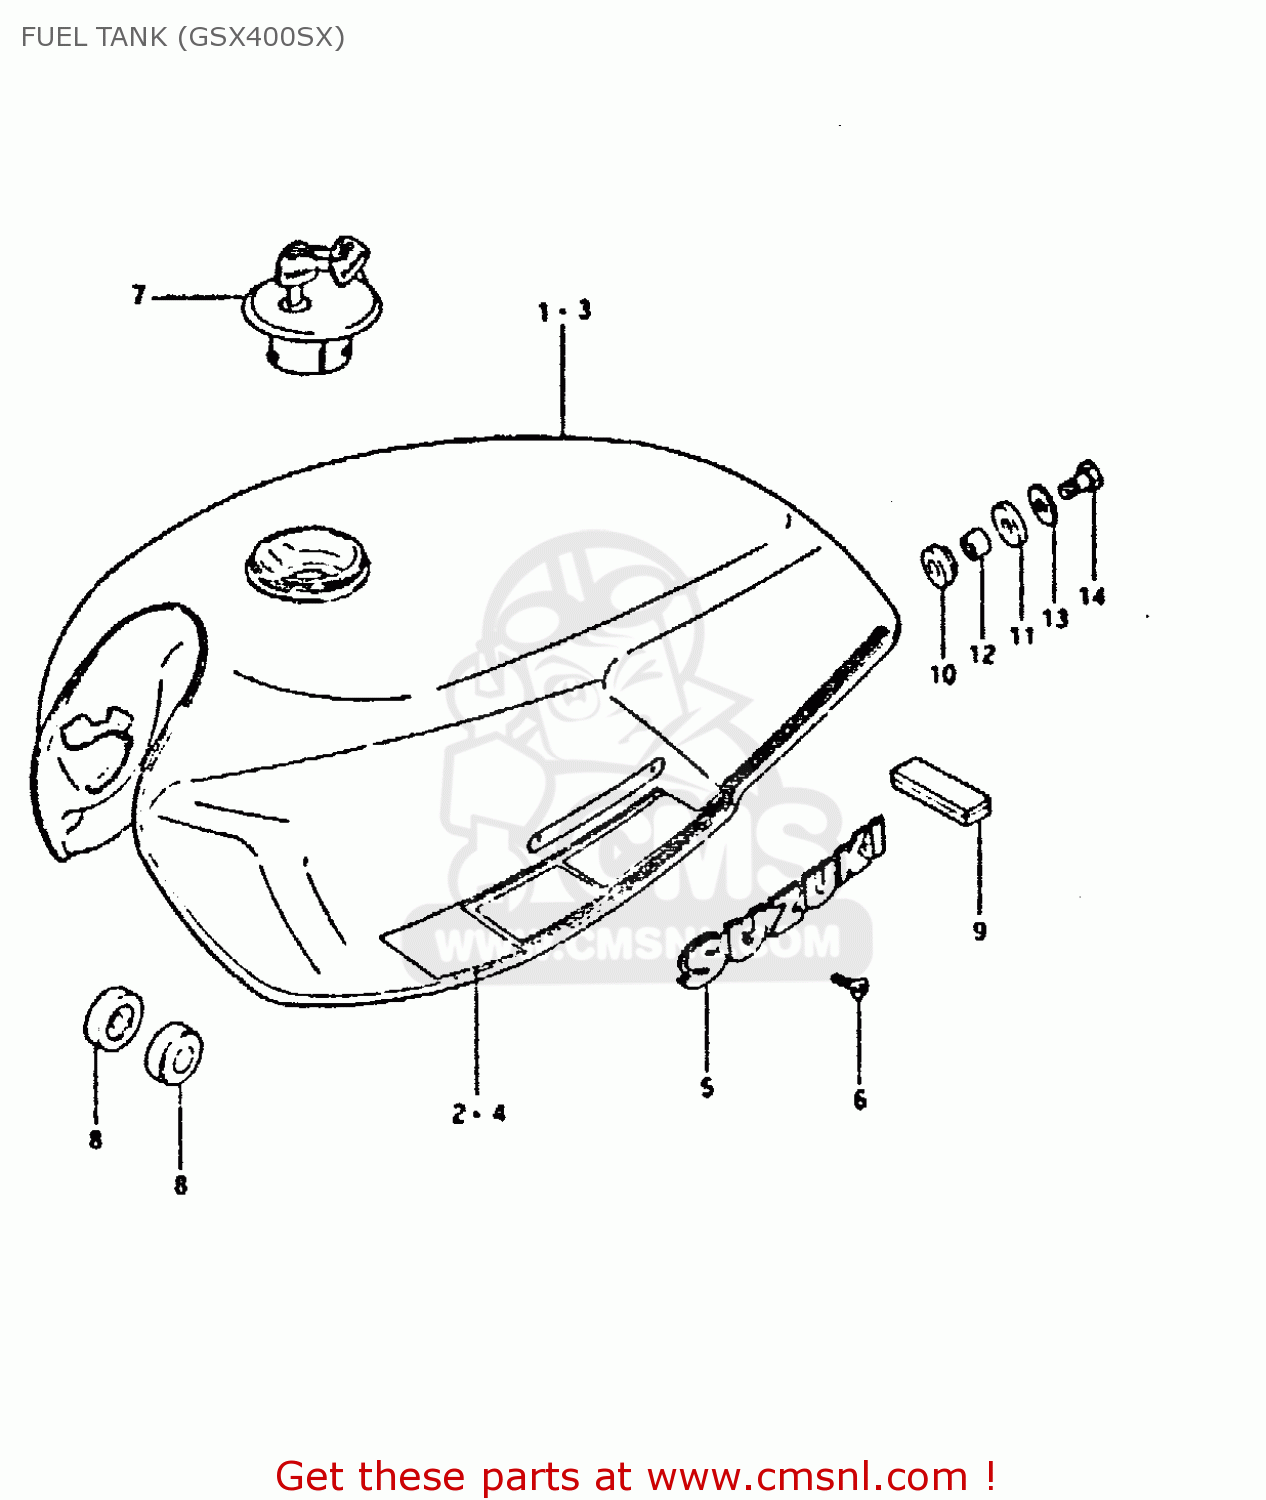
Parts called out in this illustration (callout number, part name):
1	TANK, FUEL (BLACK)
2	TAPE SET
3	TANK, FUEL (WHITE)
4	TAPE SET
5	EMBLEM
6	SCREW 3X6
7	CAP SET,FUEL TANK
8	CUSHION
9	CUSHION
10	CUSHION
11	CUSHION
12	SPACER(8.5X12X19)
13	WASHER (8.5X29X1.6)
14	BOLT (8X30)
